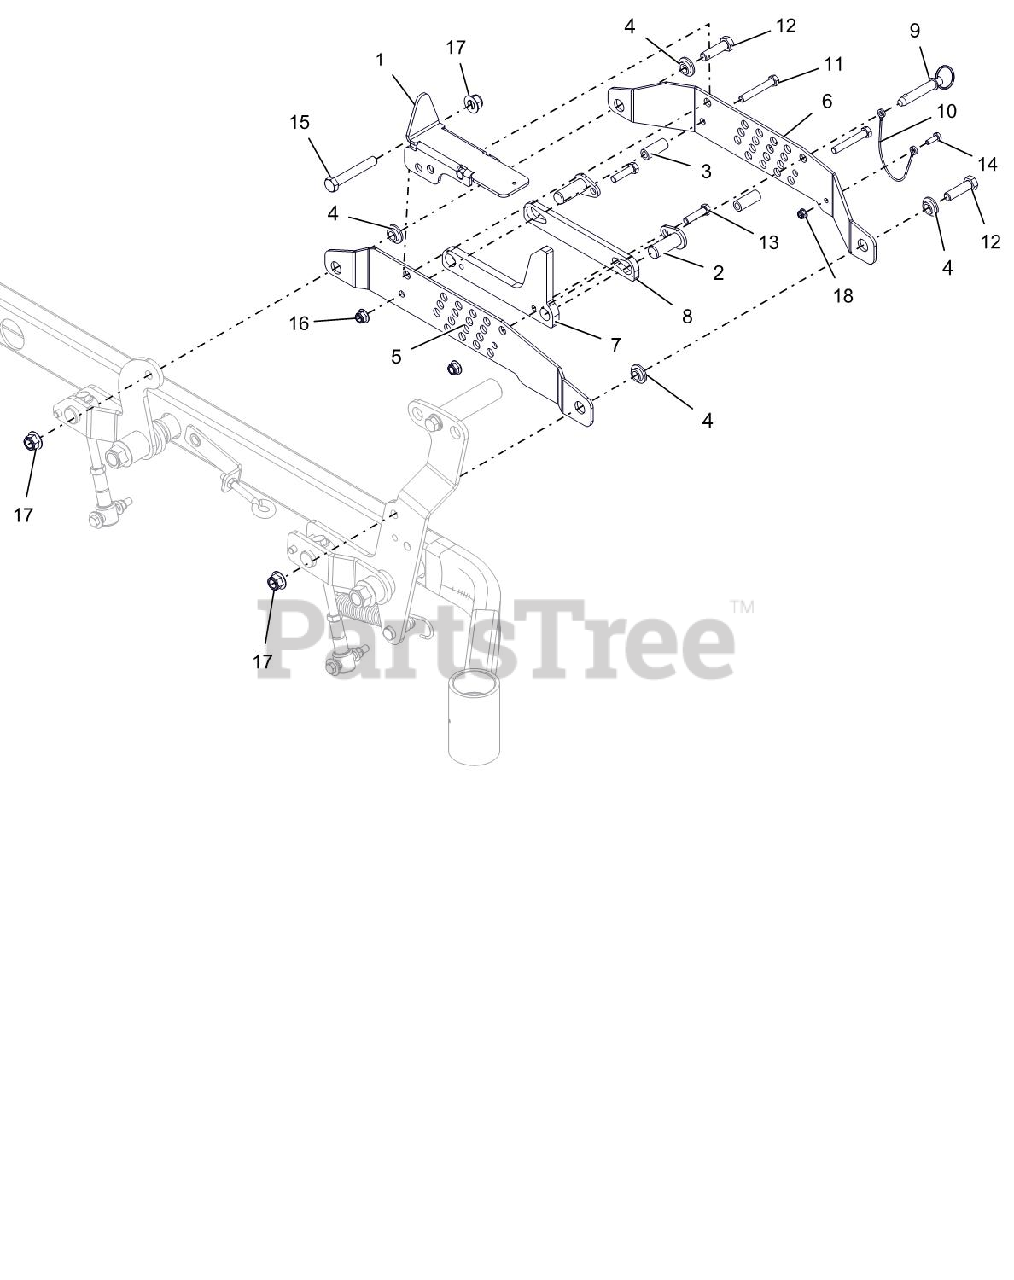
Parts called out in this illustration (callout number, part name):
1	MECHANICAL LOCK-UP WMT - BLACK
2	WLDMT, PIN HOC MOUNTING
3	SPACER, .375 X .625 X 1.54
4	BSHG-FLG .515X.750X.310X1.120
5	RH OTBRRD LIFT/CUT HT BRKT-BLK
6	RH INBRD LIFT/CUT HT BRKT- BLK
7	HOC STOP BRKT - BLK
8	HOC STOP SPACER - BLK
9	PIN, .50 X 2.00 USABLE LG BALL
10	CABLE, 12.0 LANYARD, NYLON
11	@BLT-HEX .38-16X2.50 GR5 YWZC
12	@BLT-HEX .50-13X1.75 GR5 YWZC
13	BLT,HEX .38-16X1.50 GR5 EP30
14	@BLT-HEX .25-20X.75 GR5 YWZC
15	@BLT-HEX .50-13X3.25 GR5 YWZC
16	@NUT-LK-NYL-FLG .38-16 YWZC
17	@NUT-LK-NYL-FLG .50-13 YWZC
18	@NUT-LK-NYL-FLG .25-20 YWZC
